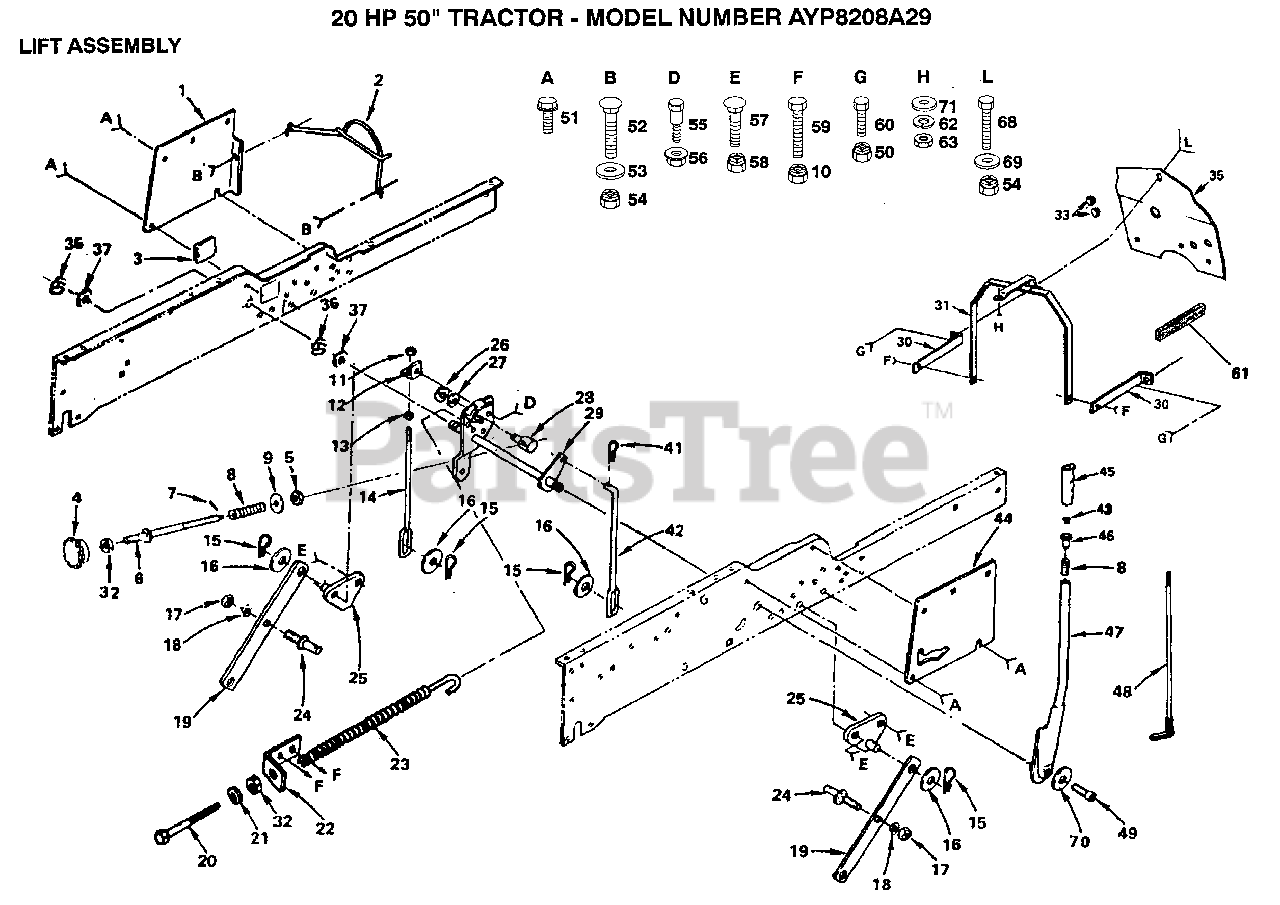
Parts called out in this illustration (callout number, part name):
2	"GUARD, BELT"
3	COVER ACCESS
5	NUT T
6	ROD ADJ. T
8	SPRING T
9	WASHER
11	NUT
12	BRACKET T
13	NUT.HEX.3/8-16UNC
14	LINK-LIFT MOW T
15	SPRING H
17	NUT
18	LOCKWASHER
19	SUSPENSION ARM GT
20	BOLT-ADJ SPRING T
21	WASHER
24	PIVOT STUD GT
25	SUSP BRACKET T
26	KLIP RING
27	WASHER
28	TRUNION LT
30	BRACKET T
32	NUT
35	"SHIELD HEAT, BASE"
36	E-RING
37	WASHER
42	LIFT LINK RH T
45	GRIP
48	LEVER ROD LT
49	"BOLT,HEX"
51	SCREW LT
52	BOLT
53	WASHER
55	SHOULDER BOLT T
56	NUT T
57	BOLT
58	LOCKNUT
59	BOLT
60	BOLT
61	FOAM STRIP T
68	BOLT
69	WASHER M
70	LOCKWASHER
71	WASHER PM
